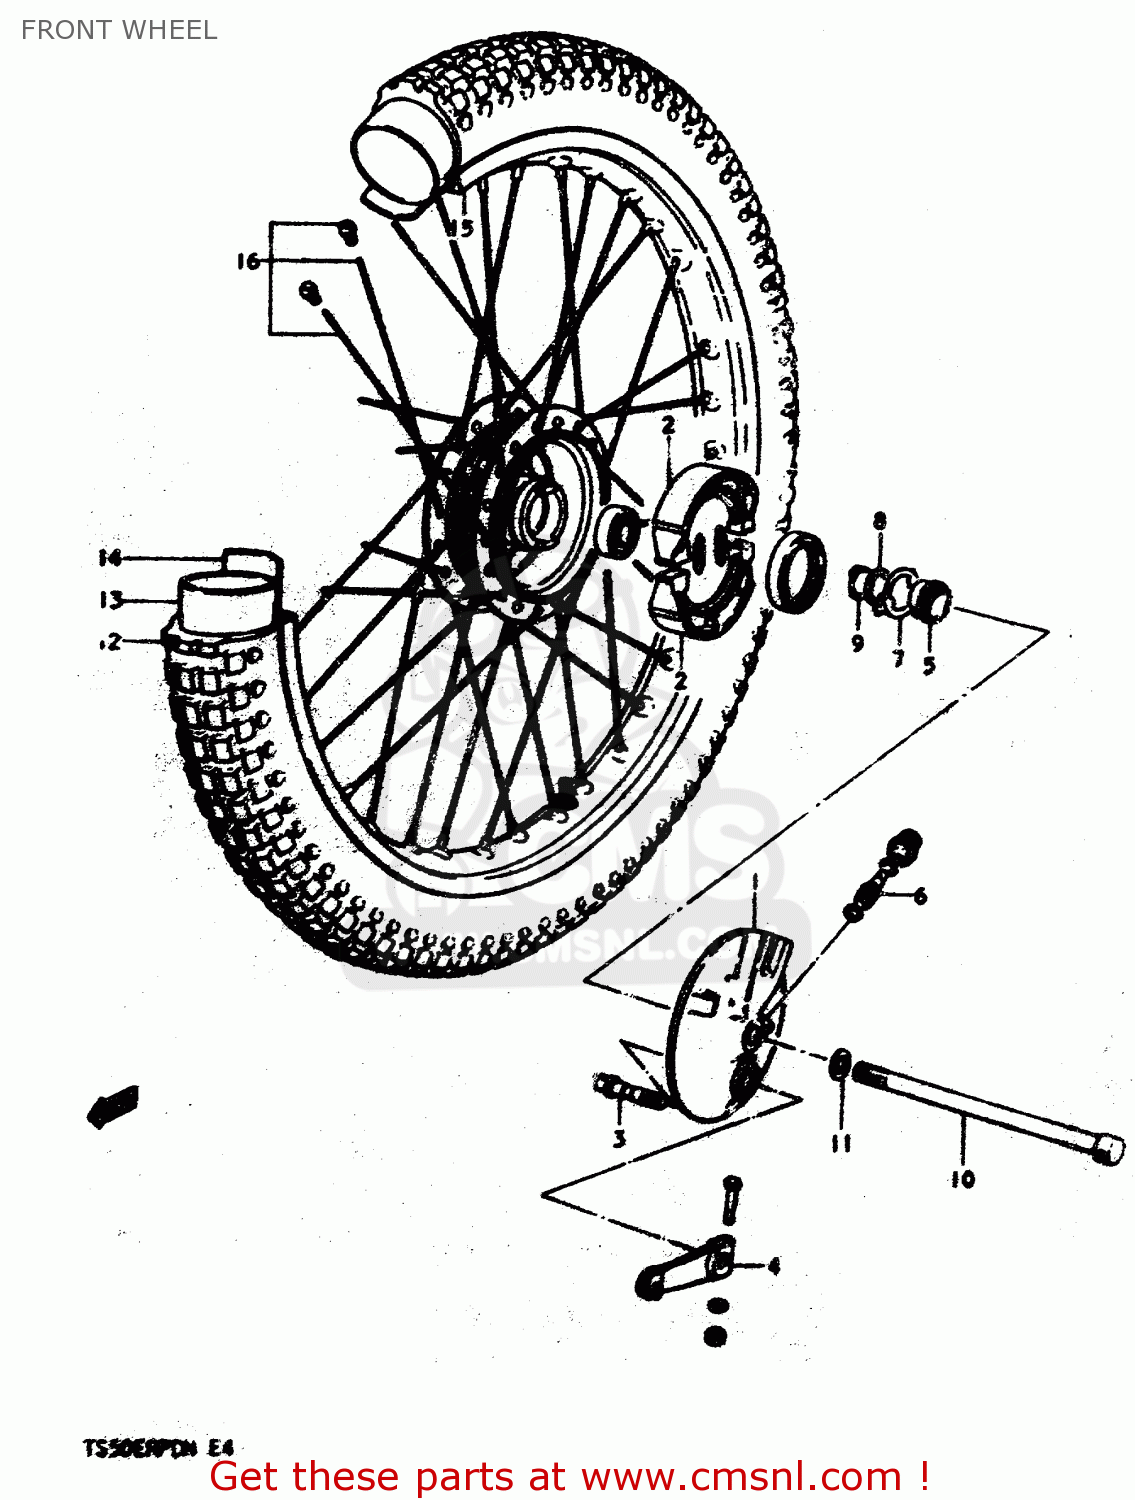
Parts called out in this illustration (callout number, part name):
1	PANEL, FRONT HUB
2	SHOE,BRAKE
3	CAM, FRONT BRAKE
4	LEVER,FR BRAKE CAM
5	GEAR,SPEEDOMETER
6	PINION,SPEEDOMETER
7	DRIVER, SPEEDOMETER GEAR
8	WASHER(18.5X24X1)
9	CIRCLIP
10	AXLE,FRONT
11	WASHER
12	TIRE,FRONT
13	TUBE
14	PROTECTOR,WHEEL,INNER
15	RIM, WHEEL
16	SPOKE SET
